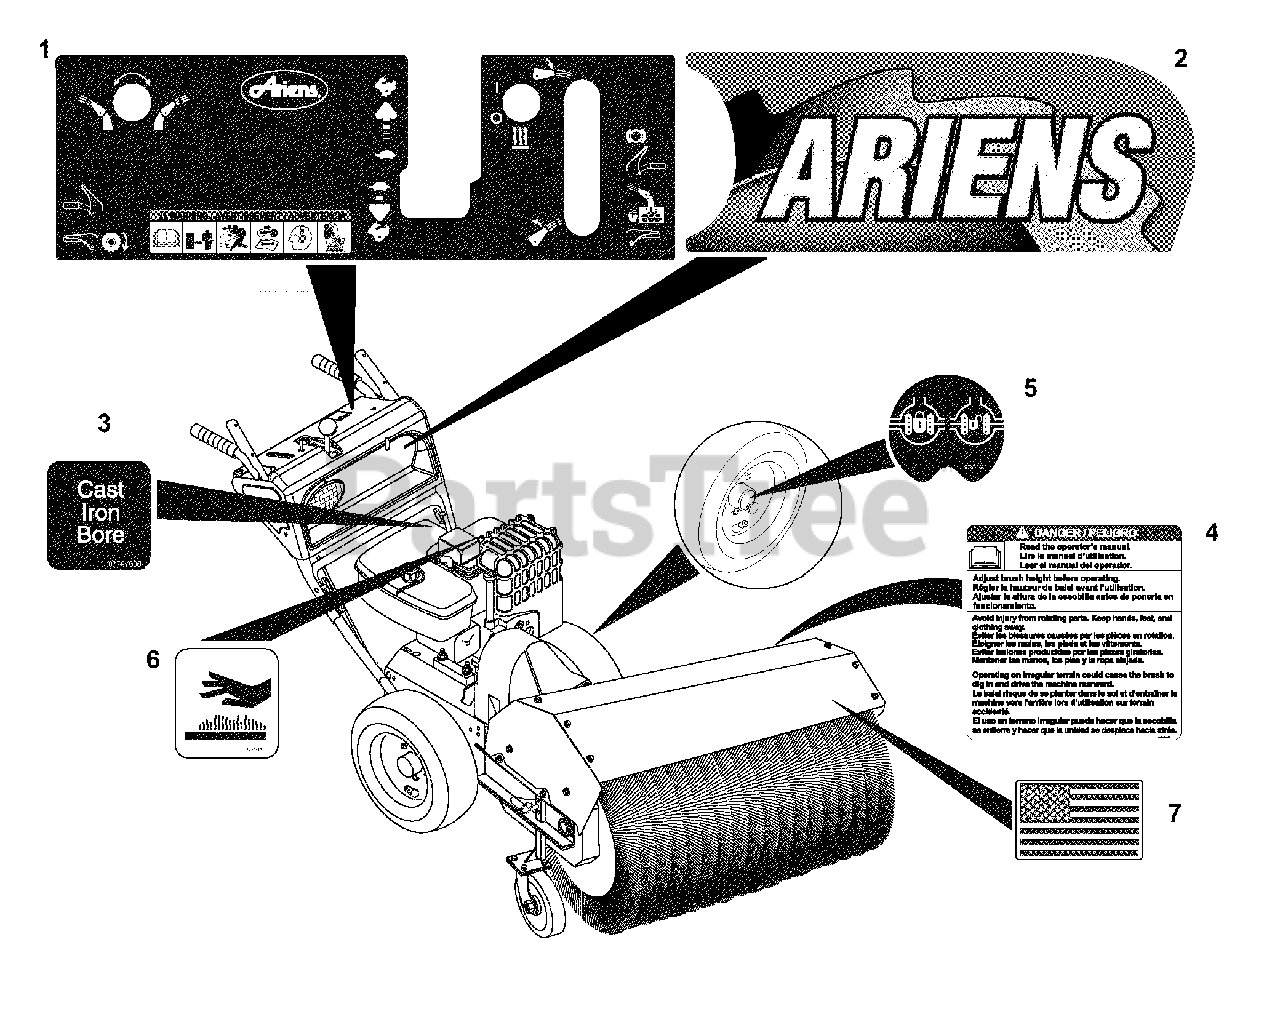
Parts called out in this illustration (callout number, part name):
1	DECAL, CONTROL - 936 ARIENS
2	DECAL, DASH - PB936 ARIENS
3	DECAL - CAST IRON BORE
4	DECAL, DANGER - POWER BRUSH
5	DIFFERENTIAL LOCK DECAL
6	DECAL, HOT SURFACE
7	DECAL, AMERICAN FLAG
